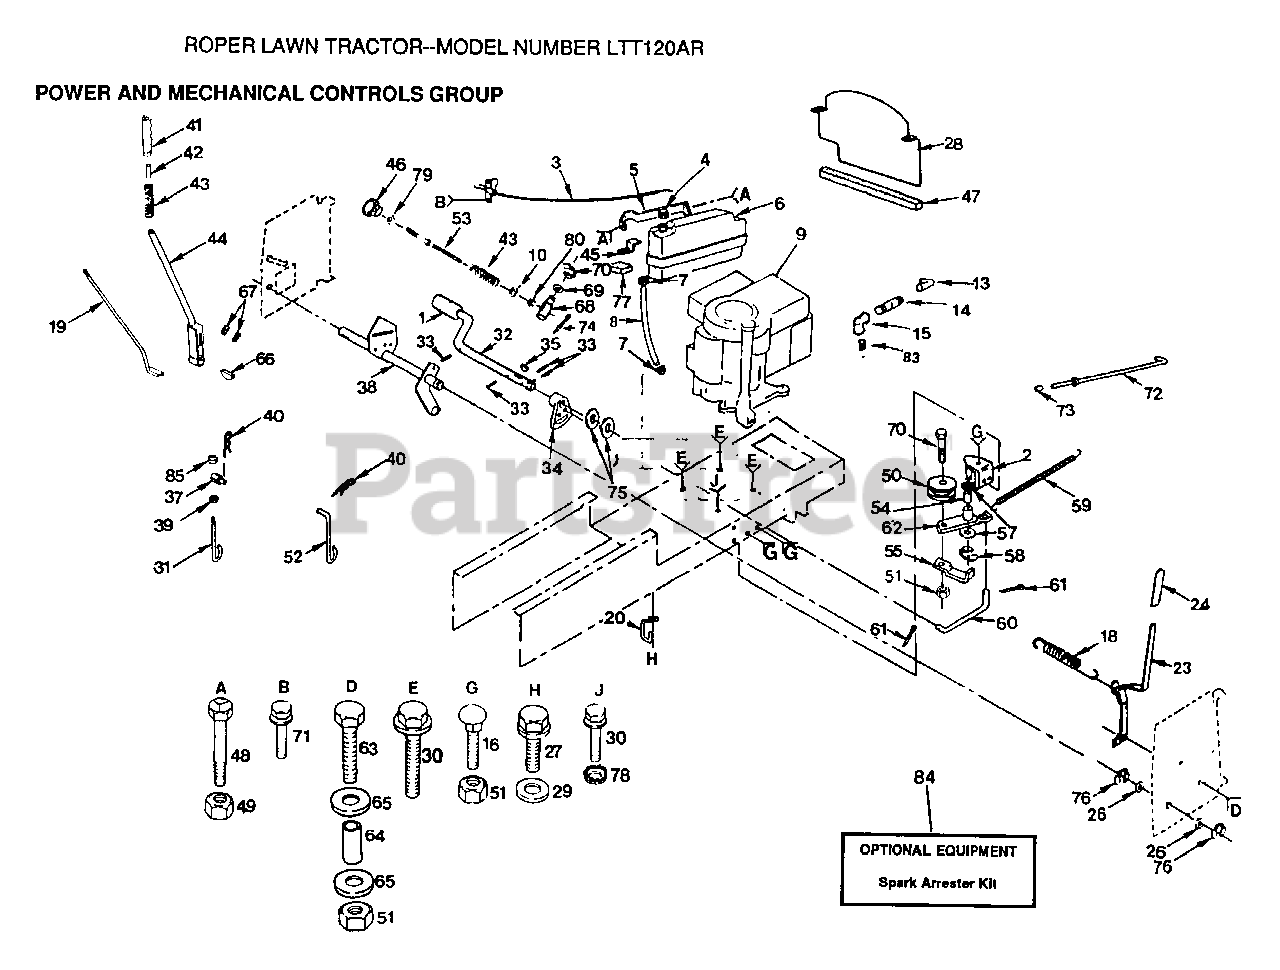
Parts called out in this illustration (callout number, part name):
1	PEDAL COVER T
5	SUPT TANK FUEL
6	FUEL TANK
8	HOSE T
10	WASHER
13	STREET ELBOW LT
14	STD PIPE NIPPLE
15	ELBOW
16	BOLT
18	"SPRING.EXT.8.5"""
19	ROD ASSY-LEVER LT
26	WASHER
27	SCREW
29	WASHER
30	SCREW
31	PIVOT PIN T
32	FOOT SHAFT PEDAL
34	ARM BRAKE LT
39	NUT
41	GRIP
43	SPRING T
44	LEVER ASSY LT
45	BRACE-TANK LT
46	HDLE ADJ LIFT
48	BOLT
52	LIFT LINK LT
53	ROD LIFT LT
54	"LY, BEARING"
57	WASHER LT
58	KLIP RING
59	"SPRING, RETURN LT"
60	"LINK, CLUTCH T"
61	COTTER PIN
69	WASHER
70	KLIP RING
71	SCREW
73	PLUNGER CAP T
75	WASHER
76	E-RING
77	PAD-SPACER T
78	LOCKWASHER
79	NUT
80	NUT T
83	PLUG T
84	SPARK ARREST KIT
